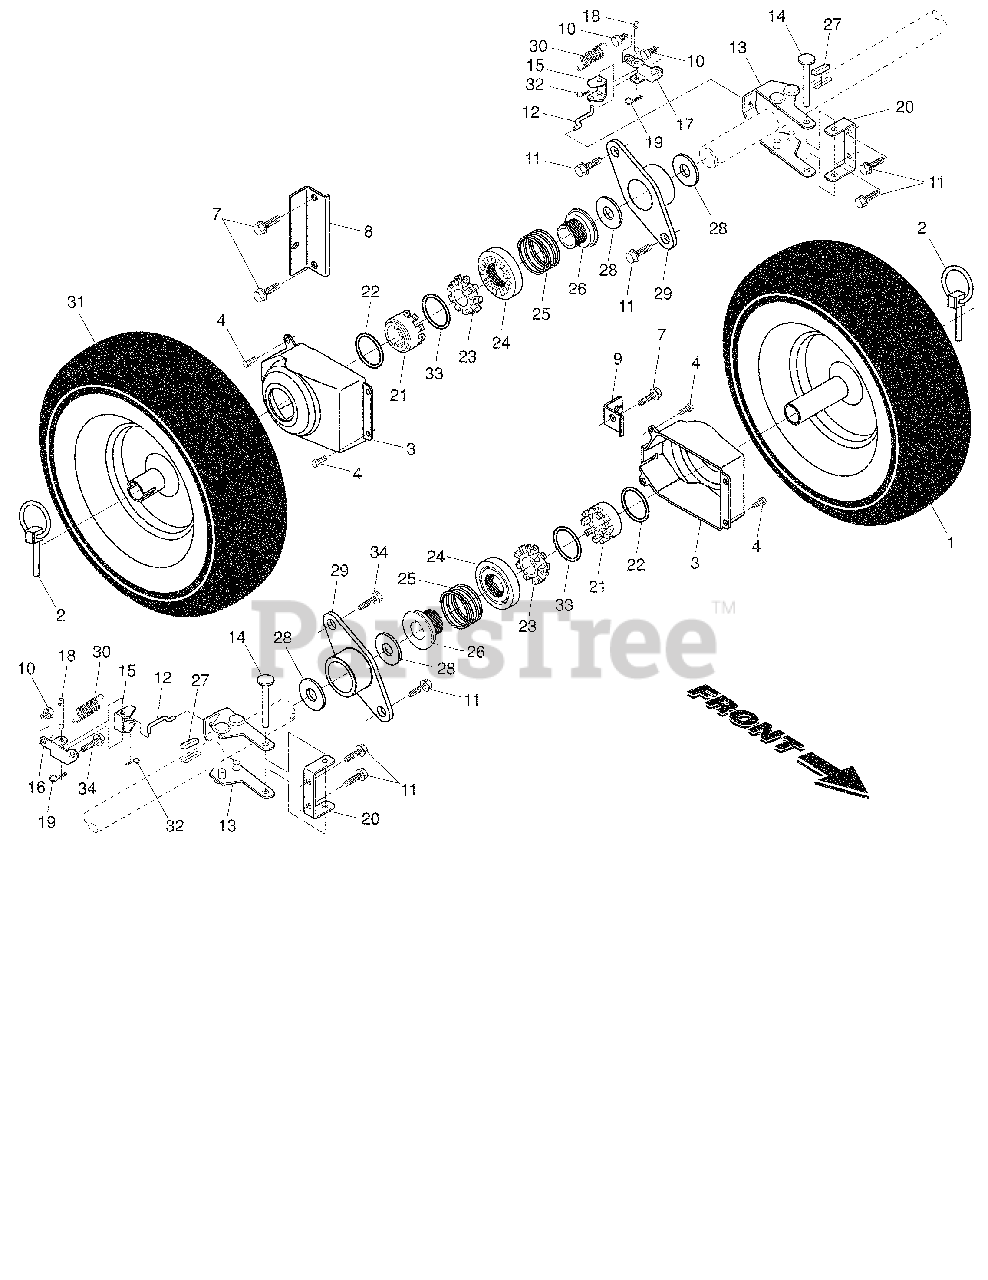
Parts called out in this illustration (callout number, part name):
1	Wheel Assembly, 16", Power Steering, LH
2	Pin, Klik 1/4
3	Cover, Power Steering
4	Bolt, Shoulder #10-24 x 5/8
7	Capscrew, Hex Head, Flanged 3/8-16 x 1
8	Bracket, Steering Cable, RH
9	Bracket, Steering Cable, LH
10	Screw, Hex Head 1/4-20 x 3/8
11	Screw, Hex Head 5/16-18 x 1/2
12	Link, Steering Yoke
13	Yoke, Steering
14	Pin, Steering Lever
15	Bellcrank
16	Bracket Assembly, LH Steering
17	Bracket Assembly, RH Steering
18	Pin, Steering Bellcrank
19	Retainer, Hairpin
20	Bracket, Steering
21	Driver, Wheel
22	Ring, Wire Retainer
23	Lobe, Wheel
24	Slide, Clutch
25	Spring, Clutch Slide
26	Lobe, Axle
27	Key, Square
28	Washer, Thrust (1")
29	Bearing, Axle
30	Spring, Return
31	Wheel Assembly, 16", Power Steering, RH
32	Clip, Retainer
33	Ring, Retaining
34	Screw, Hex Head 5/16-18 x 5/8
